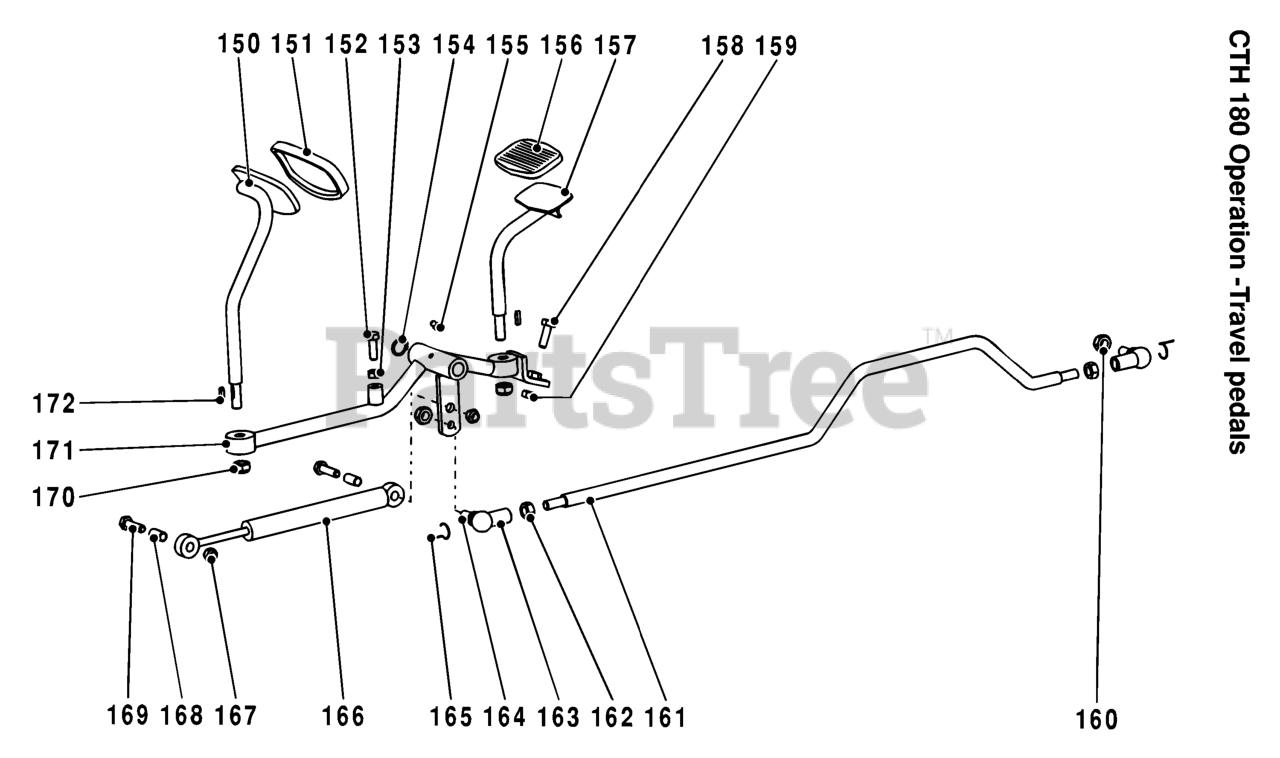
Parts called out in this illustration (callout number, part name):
153	NUT
154	RETAINING RING
159	NUT
163	BALL JOINT
164	BALL JOINT
167	NUT
